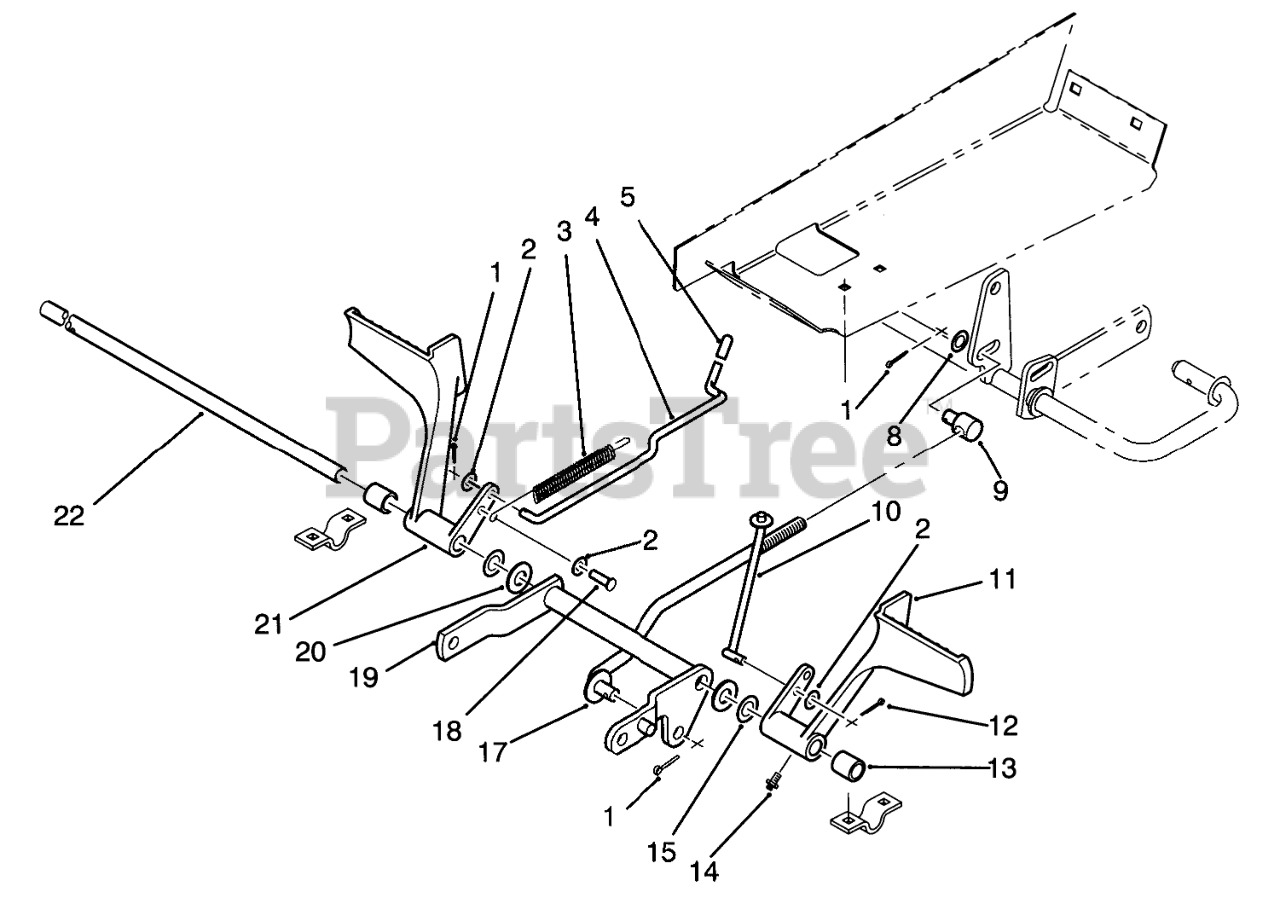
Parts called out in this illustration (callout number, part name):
1	PIN-COTTER
2	NUT-LOCK, NI
3	SPRING-BRAKE
4	ROD-BRAKE LOCK
8	WASHER-FLAT
9	ROD-TRUNNION LIFT
10	WLDMT-ROD B
11	Pedal-Clutch
12	PIN-COTTER
13	SPACER
14	Fitting-Grease
15	WASHER-WAVE
18	Pin-Clevis
19	Arm
20	Washer
21	Pedal-Brake
22	SHAFT
